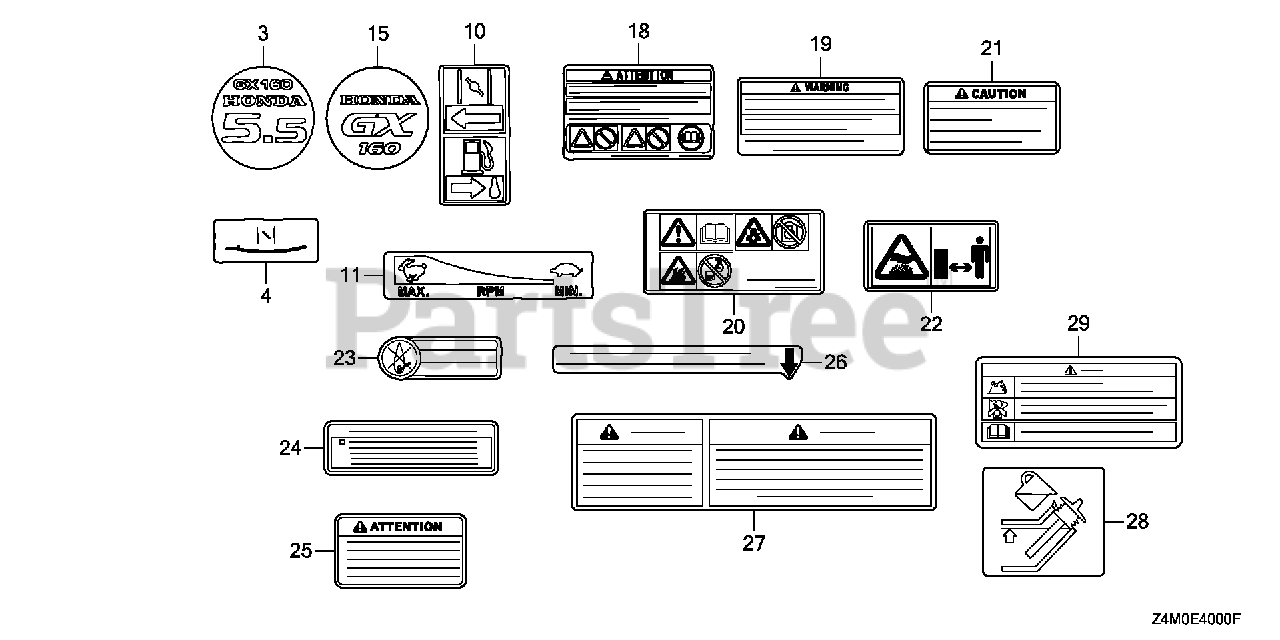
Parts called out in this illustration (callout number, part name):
19	MARK, OPERATOR CAUTION (ENGLISH)(MADE IN THAI)
19	MARK, OPERATOR CAUTION (FRENCH)(MADE IN THAI)
20	MARK, OPERATOR CAUTION (PICTOGRAPH)
21	MARK, EX. CAUTION (ENGLISH)
22	MARK, EX. CAUTION (PICTOGRAPH)
25	MARK, EX. CAUTION (FRENCH)
